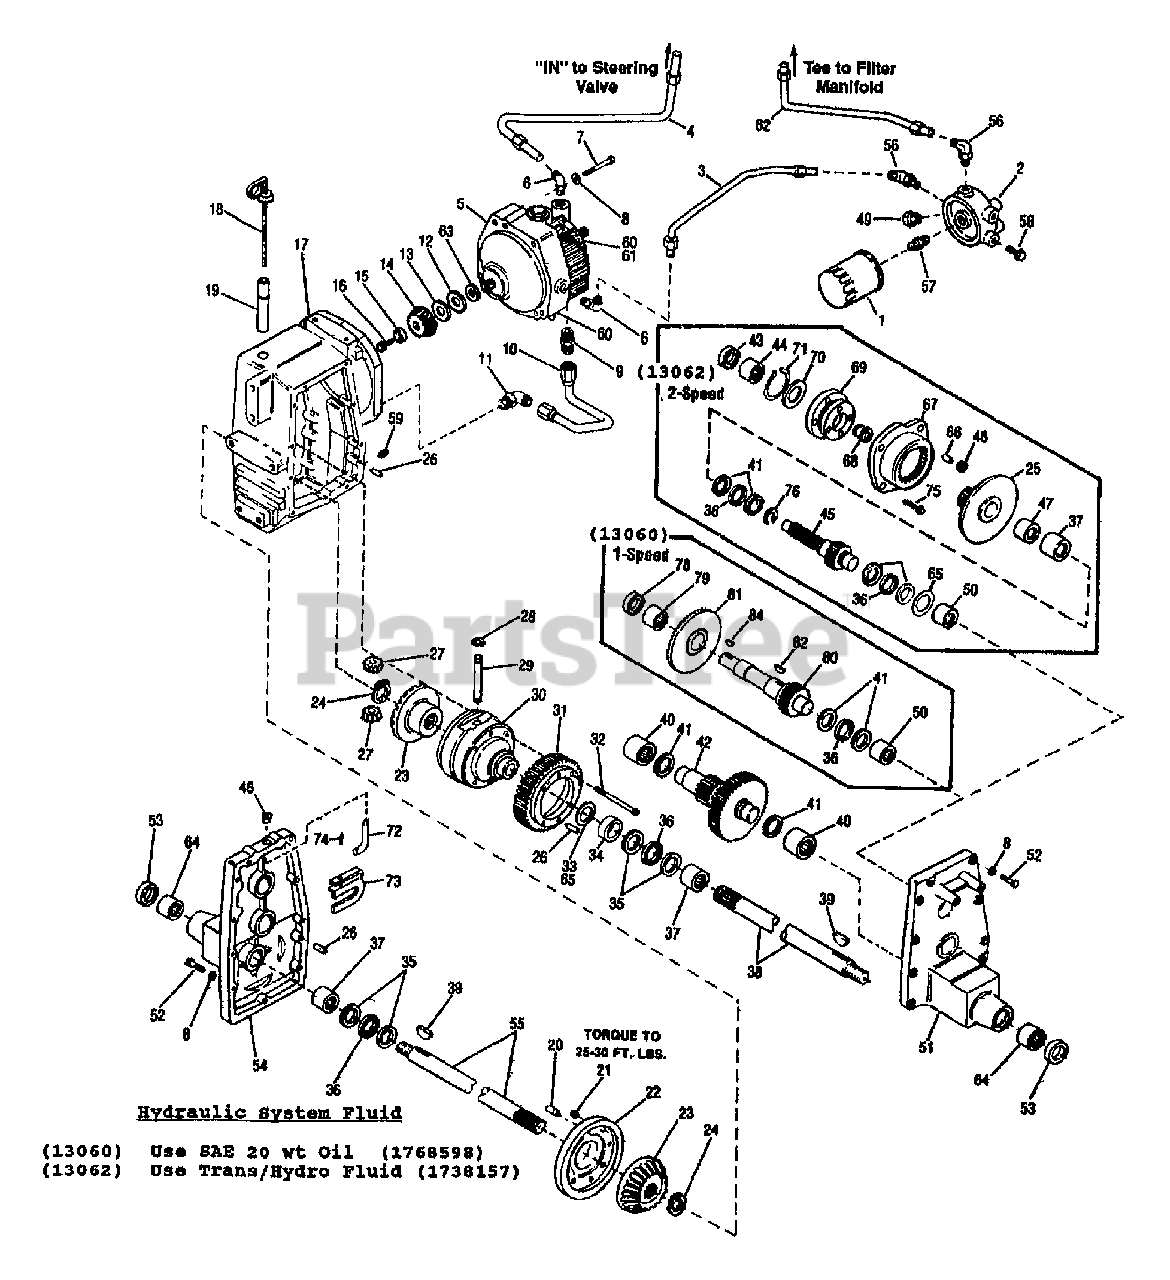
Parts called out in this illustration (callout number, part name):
1	FILTER-OIL
2	FILTER-MANIFOLD
3	ASSM-RETURN TUBE
4	ASSM-TUBE
5	EATON TRANS. MODEL 11
5	PUMP-HYDRO
6	ELBOW
7	SCR-HH 3/8-16X2.75 G5 ZP
8	WASHER-LK .375 @ DEPL
9	CONNECTOR
11	ELBOW
12	WASHER-SHIM
13	WASHER-SHIM
14	PINION-BEVEL
15	SPACER-1.0X.25X.25
16	SCR-HH 1/4-20X.625 G5 ZP
17	HOUSING-TRANSAXLE
18	DIPSTICK
20	PIN-.312X.75
21	NUT-HEX/LK 5/16-18 G5ZP
22	COVER-DIFFERENTIAL
23	GEAR-BEVEL 22T {13062}
23	GEAR-23T {13060}
24	RING-RET {13062}
24	RING-HEAVY EXT HD 1.0 ID {13060}
25	GEAR-BEVEL 23T 24T 56T {13062}
26	PIN-DOWEL .375X1.00 ZP
27	PINION-10T
28	RING-HEAVY EXT .625 ID
29	PINION-SHAFT
30	CARRIER-DIFFERENTIAL {13062}
30	CARRIER-DIFFERENTIAL {13060}
31	GEAR-AXLE 47T
32	SCR-HFLK 5/16-18X4.00 ZP
33	SHIM-1.75X1.26X.02 {13062}
33	SHIM-.005 {13062}
33	SHIM-1.875X1.013X.015 {13060}
34	SPACER-1.75X1.265X.432 {13062}
34	SPACER-1.5X1.01X.45 {13060}
35	RACE-THRUST {13062}
35	RACE-THRUST {13060}
36	BEARING-THRUST {13062}
36	BEARING-THRUST {13060}
37	BEARING-NEEDLE {13062}
38	AXLE-RH {13062}
38	AXLE-RH {13060}
39	KEY-WOODRUFF .312X1.12
40	BEARING-NEEDLE
41	RACE-THRUST {13062}
41	RACE-THRUST {13060}
42	GEAR CLUSTER {13062}
42	ASSM-GEAR CLUSTER {13060}
43	SEAL-OIL
44	BEARING-NEEDLE
45	SHAFT-PINION {13062}
46	SEAL-OIL {13062}
47	BEARING-BRONZE {13062}
48	GEAR-PLANET {13062}
49	SWITCH-TEMPERATURE {13062}
50	BEARING-NEEDLE {13062}
51	COVER-TRANS RH {13062}
51	COVER-TRANSAXLE RH {13060}
52	SCR-HH 3/8-16X1.5 G5 ZP
53	SEAL-OIL {13062}
53	SEAL-OIL {13060}
54	COVER-TRANS LH {13062}
54	COVER-TRANS LH {13060}
55	AXLE-LH {13062}
55	AXLE-LH {13060}
56	ELBOW
57	COUPLING
59	PLUG-PIPE
60	SEAL-OIL
61	SHIELD-GRASS
62	ASSM-TUBE
63	WASHER-1.0X.64X.029
64	BEARING {13062}
64	BEARING-NEEDLE {13060}
65	SHIM-.005 {13062}
66	PIN {13062}
67	GEAR-INTERNAL RING {13062}
68	GEAR-SLIDING {13062}
69	CARRIER-PLANET {13062}
70	WASHER-THRUST {13062}
71	RING-RET. INT 4 DIA {13062}
72	SHAFT-SHIFTER {13062}
73	PLATE-SHIFTER {13062}
74	PIN-ROLL .156X.75 {13062}
75	SCR 5/16-18X1.00 {13062}
76	RING-POSITIONING {13062}
78	SEAL-OIL {13060}
79	BEARING-NEEDLE {13060}
80	ASSM-PINION SHAFT {13060}
81	GEAR {13060}
82	KEY-WOODRUFF .25X1 {13060}
84	KEY-WOODRUFF .25X.75 {13060}
